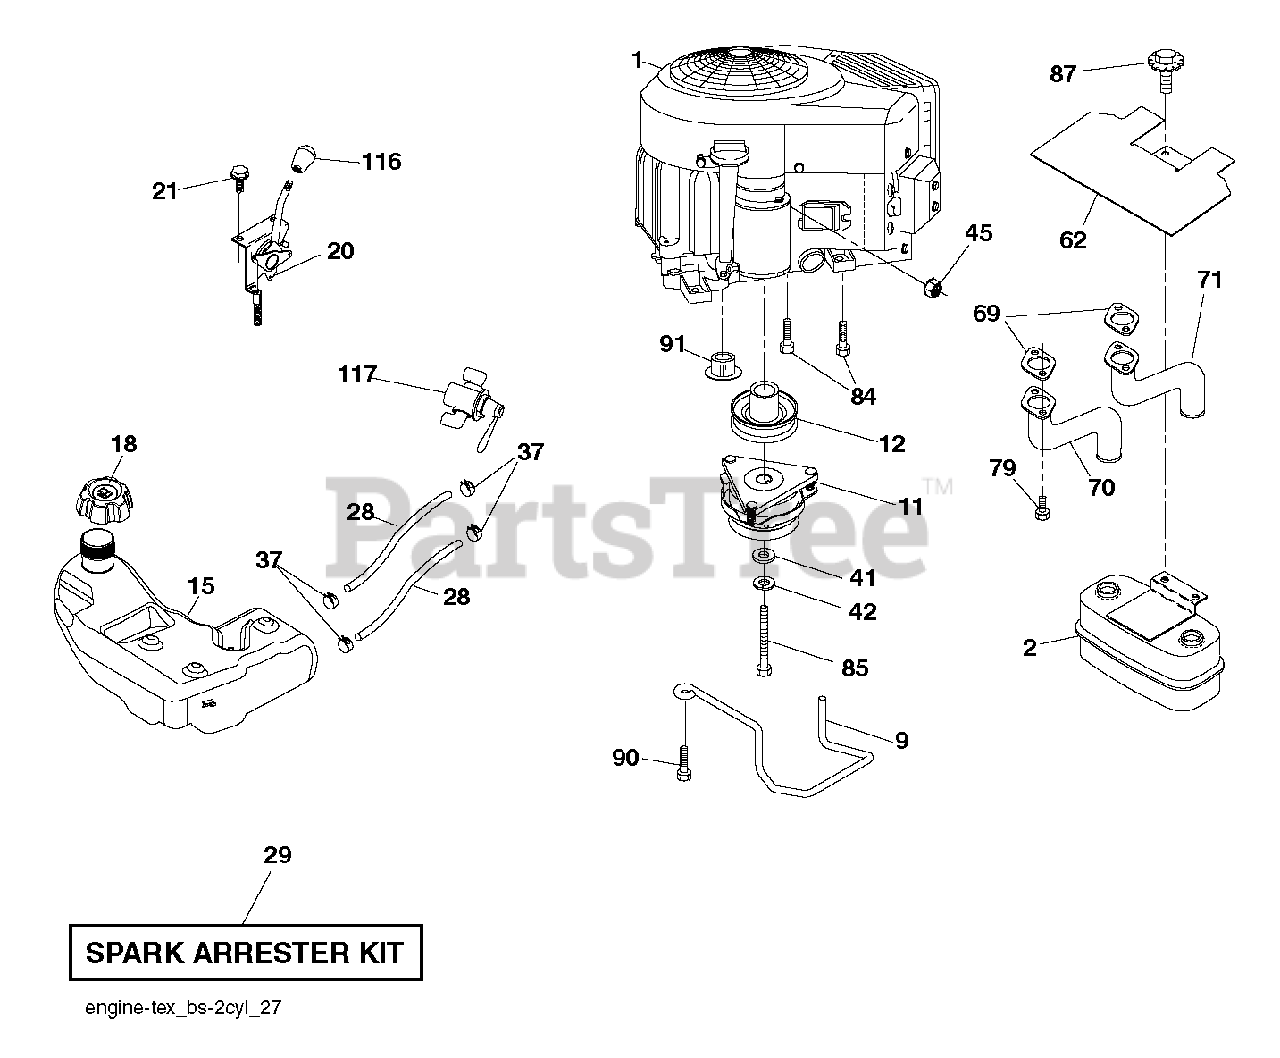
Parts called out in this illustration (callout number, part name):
2	MUFFLER.TWIN.CYL.LOW.TONE
9	KEEPER.BELT.ENGINE.4.2
11	CLUTCH.ELECTRIC.LT.48"*
12	PULLEY.ENGINE.TUFFTORQ
18	CAP.FL.R.3'N/CARB.H.CROWN.498
20	CONTROL.TH/CK.COBRA.B&S.TWN.
21	SCREW.#10 X 0.750.BOS
28	LINE.FUEL.1/4" ROLL
29	KIT.SPARK ARRESTOR 794945 B&S
37	HOSE CLAMP
42	LOCKWASHER
45	NUT
62	SHIELD.HEAT.MUFFLER
69	GASKET.MUFFLER
70	RP.EXHAUST.TUBE.LH.BS/TWIN
71	EXHAUST.TUBE.RH.BS/TWIN
79	SCREW.SOCKET.HEAD.5/16-18
84	SCREW.3/8-16
85	BOLT HEX 7/16-20X4-1/4"
87	Bolt, 5/16-18 X 1-3/4
90	SCREW 3/8-16X1
91	BUSHING.1.375OD
116	KNOB - SHIFT
117	VALVE FUEL RESERVE
